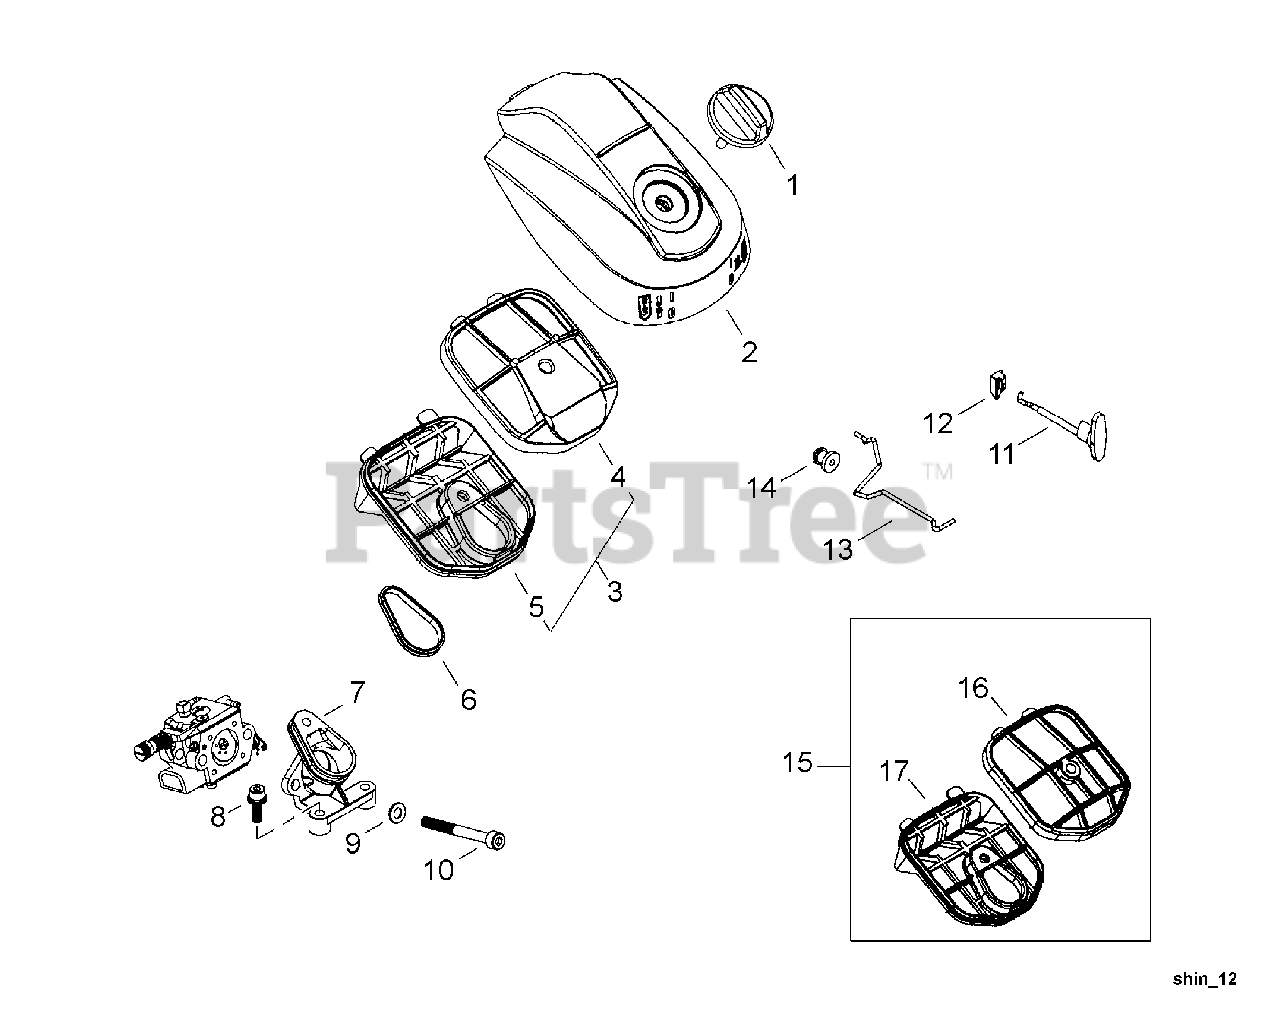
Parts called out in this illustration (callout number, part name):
1	THUMBSCREW
2	COVER, AIR FILTER
3	FILTER ASSY, 300 MESH AIR
4	FILTER, 300 MESH UPPER AIR
5	FILTER, 300 MESH LOWER AIR
6	GASKET
7	ADAPTOR, AIR FILTER
8	BOLT M4×16
9	WASHER, FLAT 5.5×10×0.8
10	BOLT M5×48
11	ROD, CHOKE
12	GROMMET, CHOKE ROD
13	ROD, THROTTLE
14	GROMMET
15	FILTER ASSY, 200 MESH AIR
16	FILTER, FLOCKED UPPER AIR
17	FILTER, FLOCKED LOWER AIR
